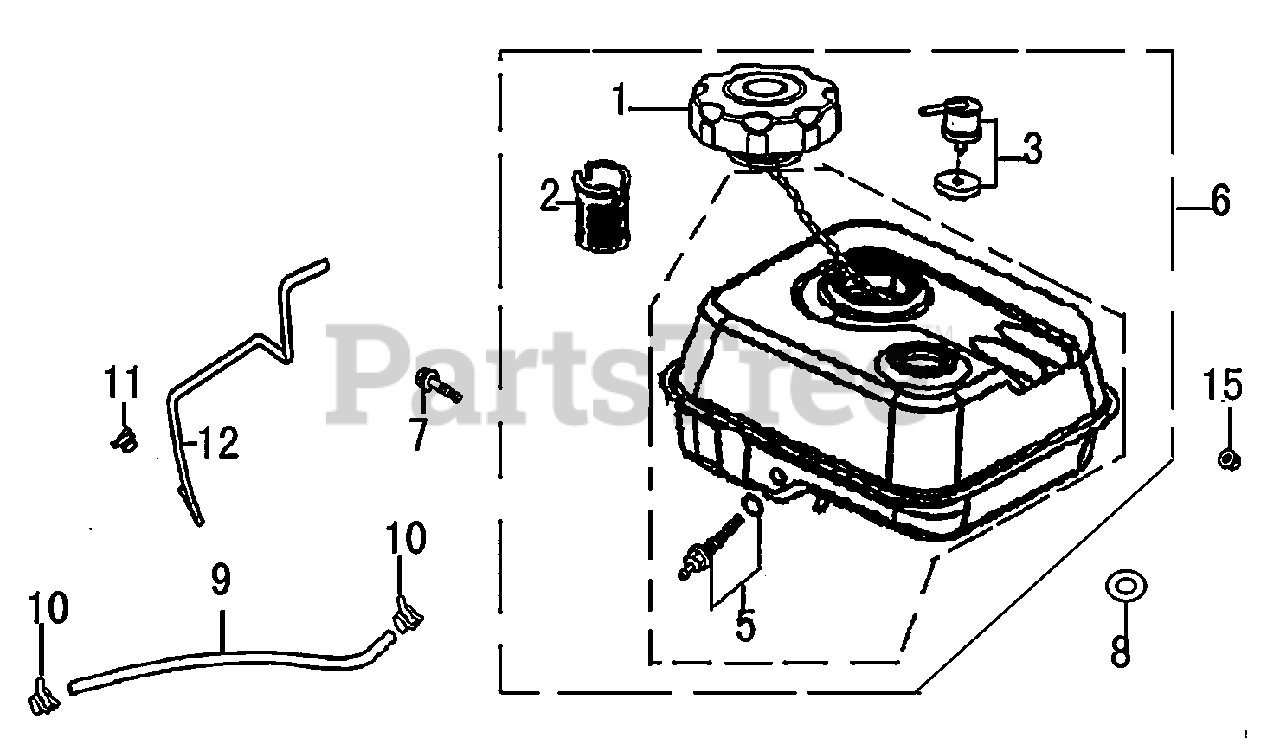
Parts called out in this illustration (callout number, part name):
1	CAP ASSY., FUEL FILLER
2	FILTER, FUEL
3	GAS VALVE, FUEL TANK
5	JOINT ASSY., FUEL TANK
6	TANK ASSY, FUEL
7	BOLT, FLANGE , 6X25
8	WASHER, RUBBER
9	HOSE, FUEL
12	HOSE, FORMED
15	NUT, FLANGE
